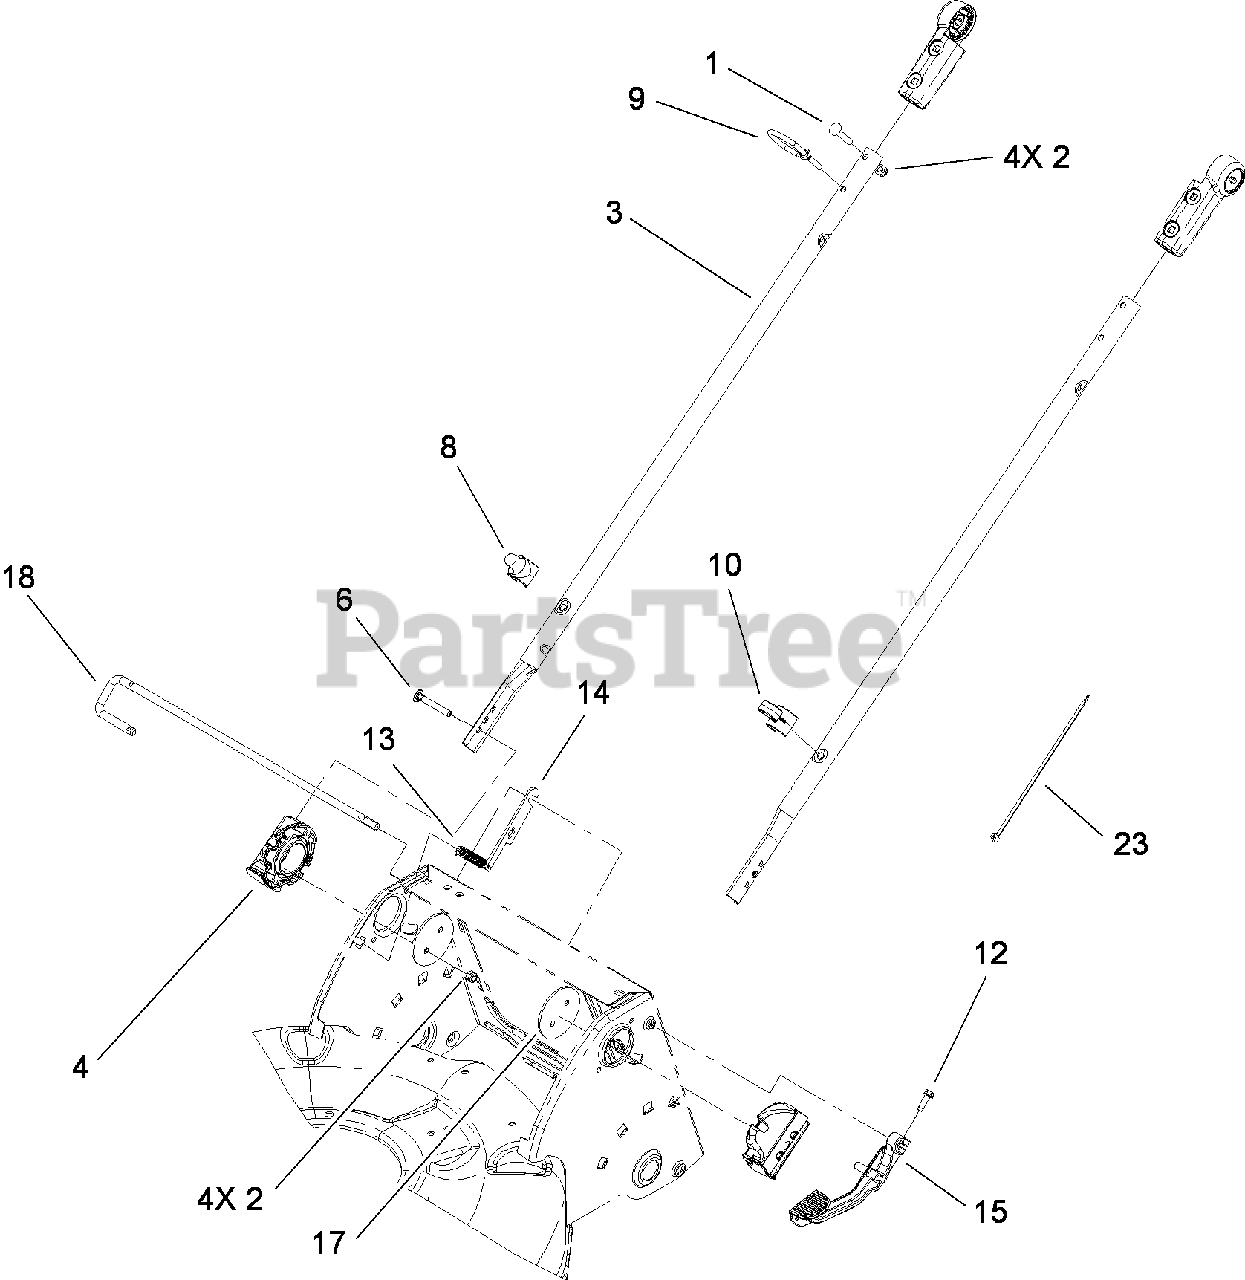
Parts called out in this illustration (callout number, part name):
1	SCREW-CARR
2	NUT-LOCK, NI
4	MOUNT-HANDLE, LOWER
8	GUIDE-ROPE, LOWER
9	GUIDE-ROPE, UPPER
10	Guide-Cable
12	SCREW-HWHTF
13	SPRING-EXTENSION
14	PLATE-ROD, RELEASE
15	LEVER-RELEASE
18	ROD-RELEASE, HANDLE
23	STRAP-TIE
